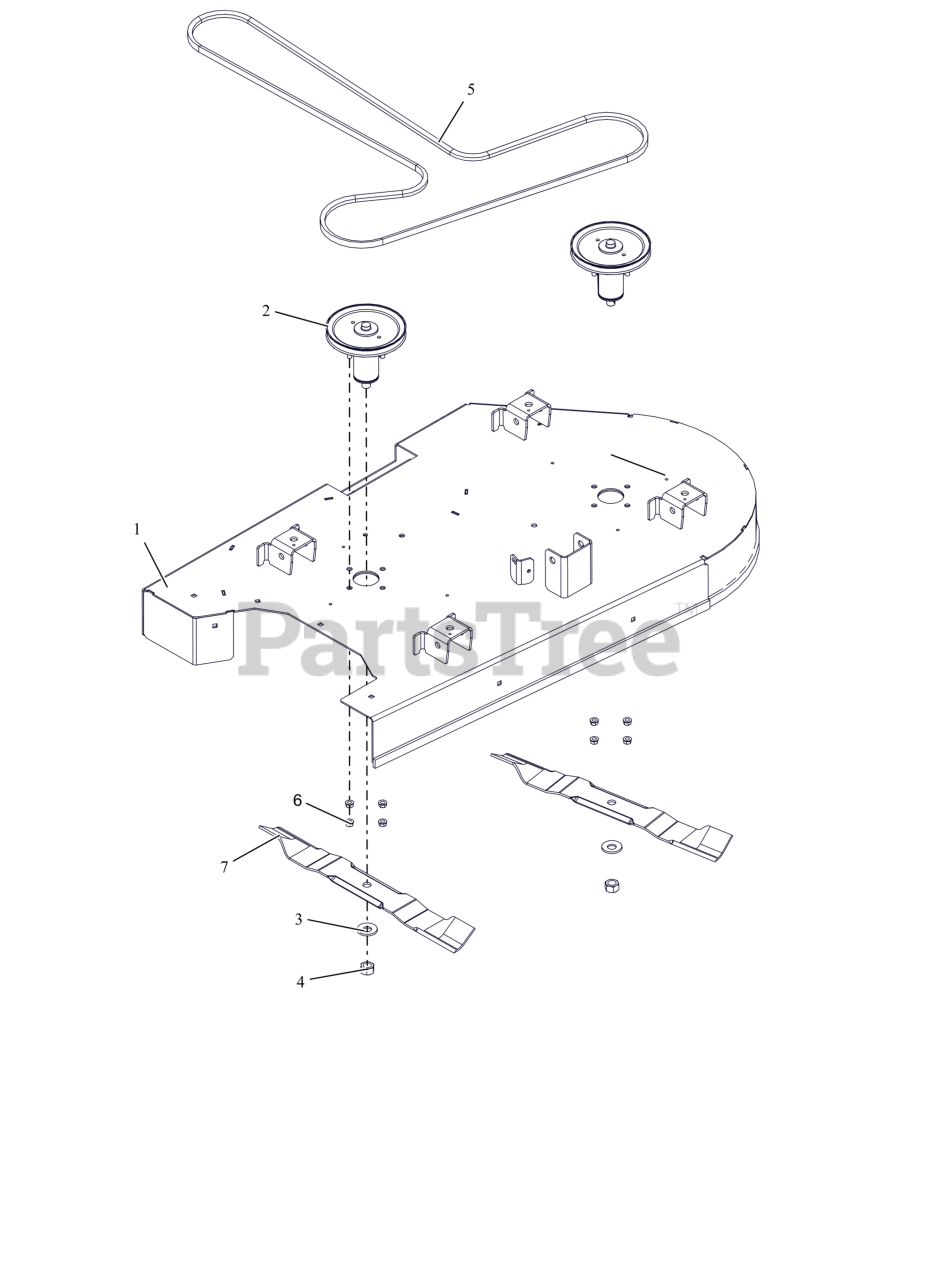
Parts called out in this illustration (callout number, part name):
1	WLDMT, DECK - 42"
2	KIT- DECK SPINDLE ASSM
3	WSHR-BLVL .669X1.535X.138
4	NUT-STD .625-18 ZCC
5	V-BELT, HA-WRAPPED
6	NUT,LK-CTR-FLG .31-18 GF ZCC
7	BLADE, 21" 35 DEG
